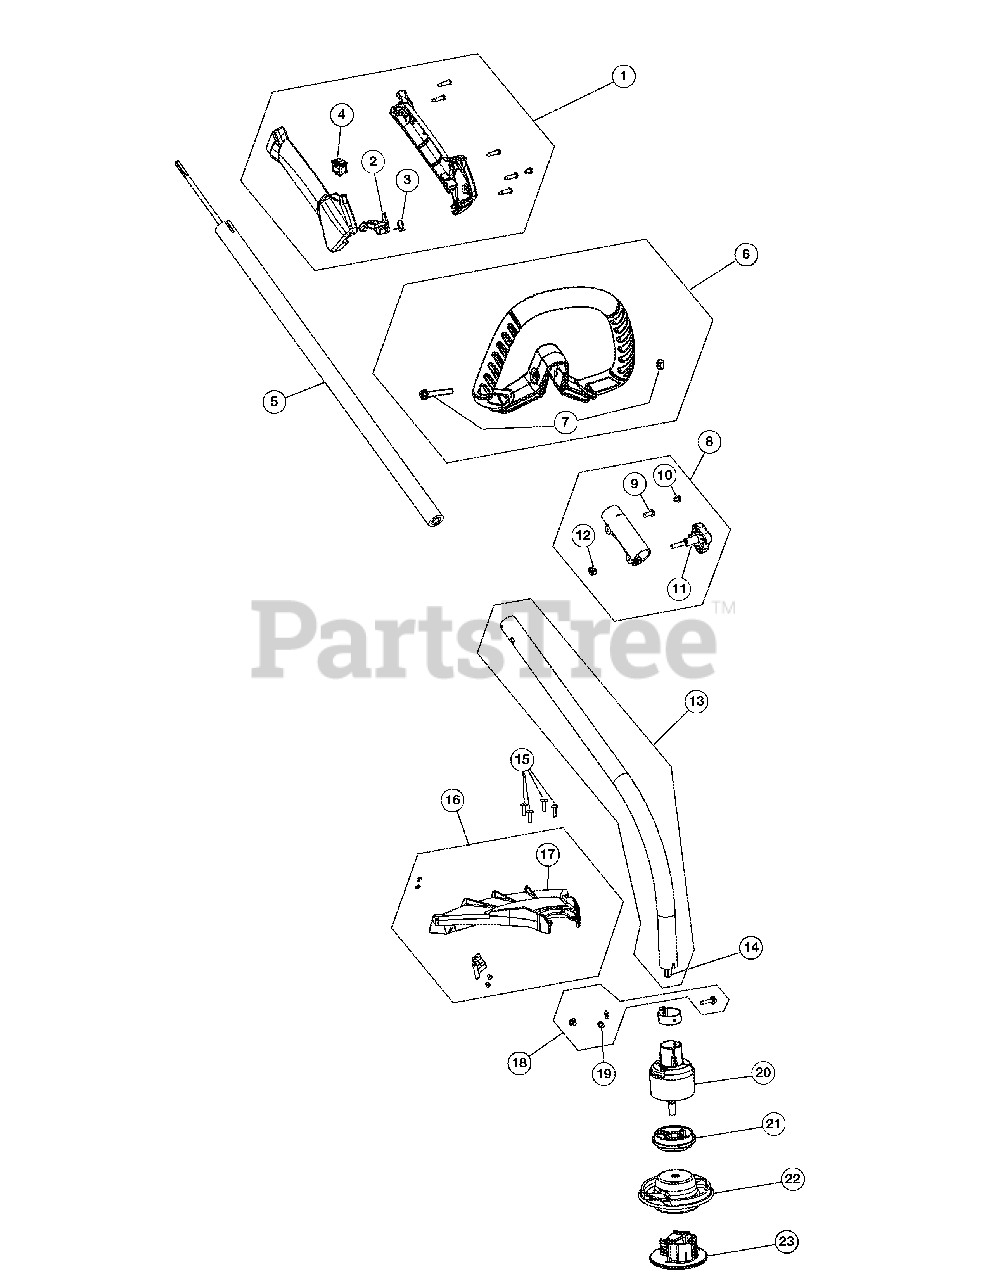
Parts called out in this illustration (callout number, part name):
1	Throttle Housing Assembly (Incl. Ref No. 2-4)
2	Throttle Trigger
3	Throttle Trigger Spring
4	Switch Assembly
5	Upper Drive Shaft Housing
6	Deluxe D-Handle Assembly (Incl. Ref No. 7)
8	Click Link Coupler (Incl. Ref No. 9-12)
11	Adjustment Knob (Incl. Ref No. 12)
13	Lower Drive Shaft Housing (Incl. Ref No. 14)
14	Lower Flexible Drive Shaft
15	Shield Mount Hardware
16	Blade Assembly
17	Shield Assembly (Incl. Ref No. 16)
18	Lower Clamp Assembly (Incl. Ref No. 19)
19	Anti-Rotation Screw
20	Bushing Housing Assembly
21	Adapter
22	Cutting Head Assembly
23	Glide Plate
